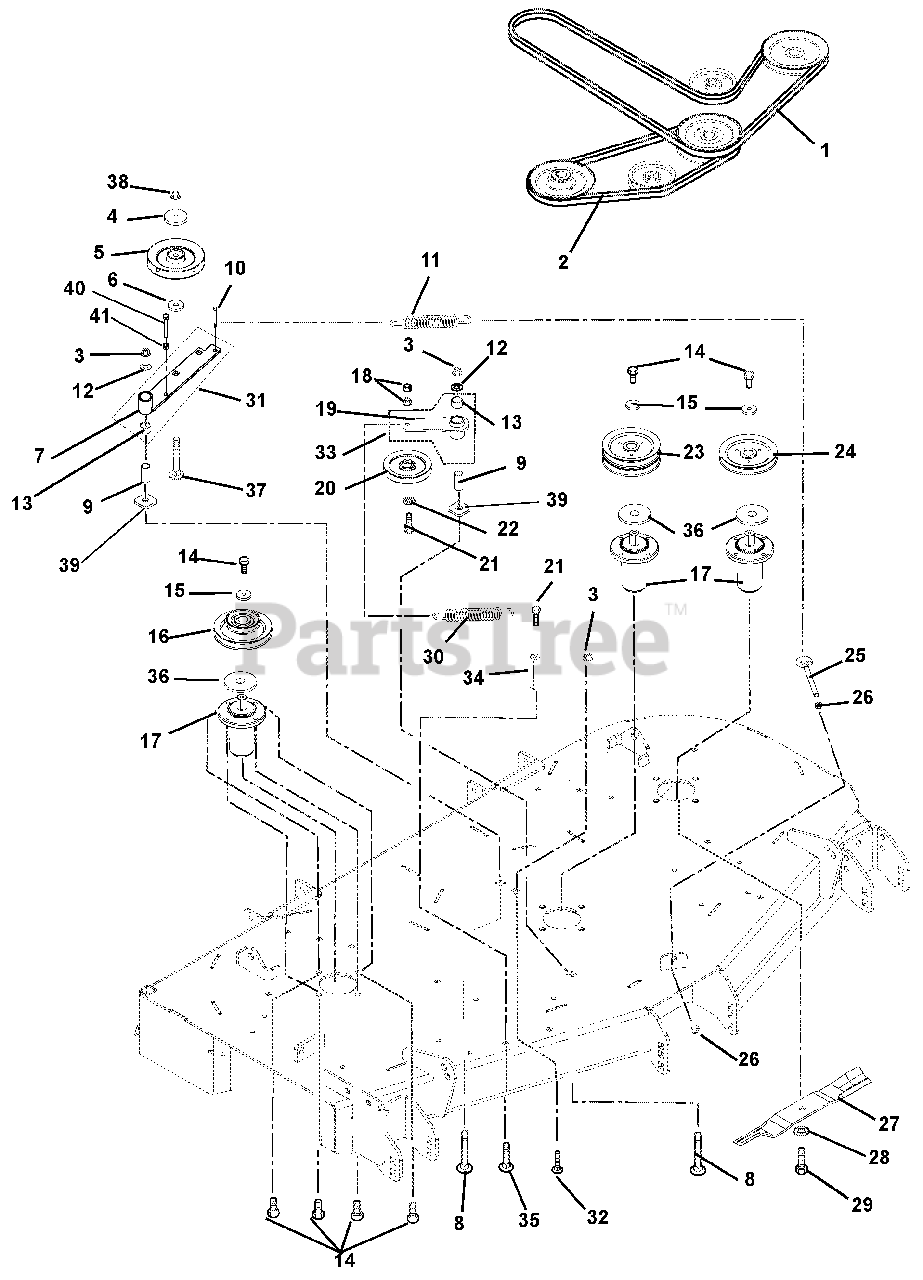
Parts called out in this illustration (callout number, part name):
1	Belt, 184.4" Long, PTO Drive Hex (215)
2	V-Belt, 63" Long Cog B-Section (215)
3	Nut, .50-13 Nyloc Flange
4	Cap, Idler Bearing Sealing
5	Sheave, .50"ID x 6.00"OD V-Idler
6	Bushing, Spacer .502 x .997 x .50
7	Weldment, Idler Arm
8	Bolt, Round Head Square Neck .50-13 x 3.50 Grade 5
9	Bushing, Spacer .505/.500 x .999/.996 x 2.05/2.03
10	Bolt, Shoulder EP .38-16 x .30 Hex
11	Spring, Extension (Deck Idler)
12	Washer, Flat Steel .563 x 1.38 x .109
13	Bushing, 1.00 x 1.125 x 1.936
14	Bolt, Hex .38-16 x 1.00
15	Washer, Flat Steel .406 x 1.50 x .245
16	Sheave, Double, 1" ID x 6.75" x 4.25" OD (215)
17	Spindle Assembly (216)
18	Nut, Locking Center .38-16
19	Weldment, Idler Arm
20	Assembly, V-Idler 5.00 O.D.
21	Bolt, Hex .38-16 x 2.25
22	Washer, Flat Steel .406 x .812 x .065
23	Sheave, Double 1" ID x 6.75" OD (215)
24	Sheave, Single 1" ID x 6.75" OD (215)
25	Bolt, .38-16 x 5.50 .62 Diameter Eye
26	Nut, Hex, Jam .375-16
27	Blade, Mower (20.50") (215)
28	Washer, Bellville .63 x 1.625 x.14
29	Bolt, Hex .62-18 x 1.75 Grade 8
30	Spring, Extension
31	Assembly, PTO Idler Pivot Arm (Includes item # 7 and item # 13)
32	Bolt, Round Head Square Neck .50-13 x 1.5, Full Thread, Grade 5
33	Assembly, Idler Arm (Includes item # 13 and item # 19 )
34	Nut, Coupling .375-16 x 1.75
35	Bolt, Round Head Square Neck .38-16 x 1.00
36	Retainer, Grease
37	Bolt, Round Head Square Neck .50-13 x 3.00 Grade 5
38	Nut .50-13 Nyloc Flange
39	Washer, Flat .640 x 1.75 x .250
40	Bolt, Hex .38-16 x 2.75
41	Nut, Hex .38-16
